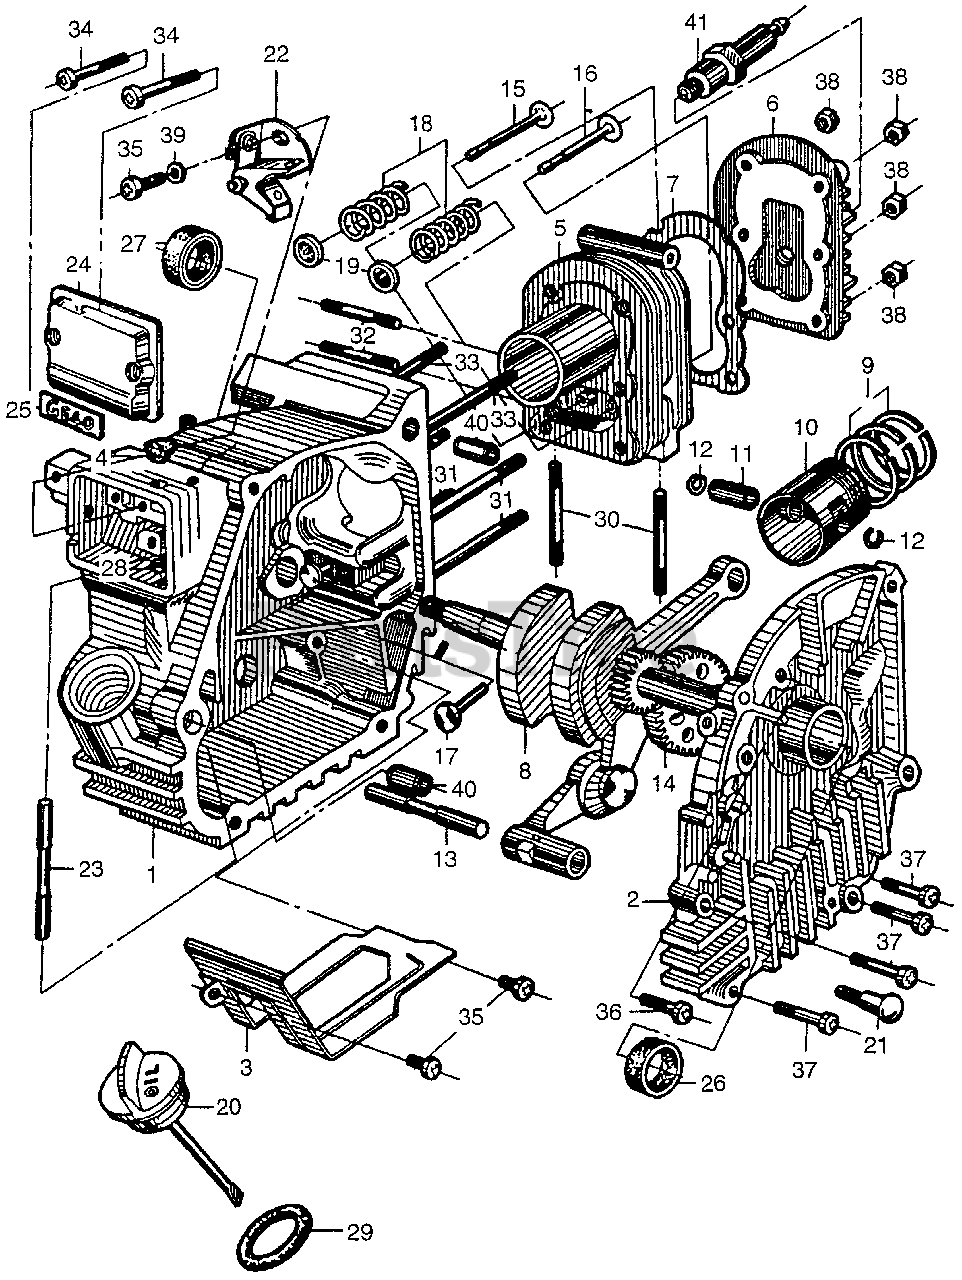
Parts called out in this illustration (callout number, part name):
1	CRANKCASE (NOT AVAILABLE)
2	COVER, CRANKCASE
3	SEPARATOR, OIL
4	CAP, SEALED
5	CYLINDER (NOT AVAILABLE)
6	CYLINDER HEAD (NOT AVAILABLE)
7	GASKET, CYLINDER HEAD (NOT AVAILABLE)
8	CRANKSHAFT ASSY. (NOT AVAILABLE)
9	RING SET, PISTON (NOT AVAILABLE)
10	PISTON (STD) (NOT AVAILABLE)
10	PISTON (OVER SIZE) (0.50) (NOT AVAILABLE)
10	PISTON (OVER SIZE) (0.75) (NOT AVAILABLE)
10	PISTON (1.00) (NOT AVAILABLE)
11	PIN, PISTON (NOT AVAILABLE)
12	CLIP, PISTON PIN (NOT AVAILABLE)
13	SHAFT, BALANCER WEIGHT
14	CAMSHAFT (NOT AVAILABLE)
15	VALVE, IN.
16	VALVE, EX. (NOT AVAILABLE)
17	LIFTER, VALVE (NOT AVAILABLE)
18	SPRING, VALVE (NOT AVAILABLE)
19	RETAINER, VALVE SPRING
20	CAP, OIL FILLER (NOT AVAILABLE)
21	HOOK, STARTER SPRING (NOT AVAILABLE)
22	POINTS (NOT AVAILABLE)
23	ROD, POINT PUSH (NOT AVAILABLE)
24	COVER, POINT (NOT AVAILABLE)
25	MARK, POINTS COVER (NOT AVAILABLE)
26	OIL SEAL (NOT AVAILABLE)
27	OIL SEAL (NOT AVAILABLE)
28	OIL SEAL (52X10X3) (NOT AVAILABLE)
29	O-RING (16MM)
29	O-RING (15.8X2.4) (SHOWA)
30	BOLT, STUD (5X48) (NOT AVAILABLE)
31	BOLT, STUD (5X58) (NOT AVAILABLE)
32	BOLT, STUD (5X24) (NOT AVAILABLE)
33	BOLT, STUD (5X63)
34	SCREW, PAN (4X28) (NOT AVAILABLE)
35	SCREW, PAN (5X10)
36	SCREW, PAN (5X25)
37	SCREW, PAN (5X32)
38	NUT, HEX. (5MM)
39	WASHER, PLAIN (5MM)
40	PIN A, DOWEL (8X12)
41	SPARK PLUG (CR40/C50)
